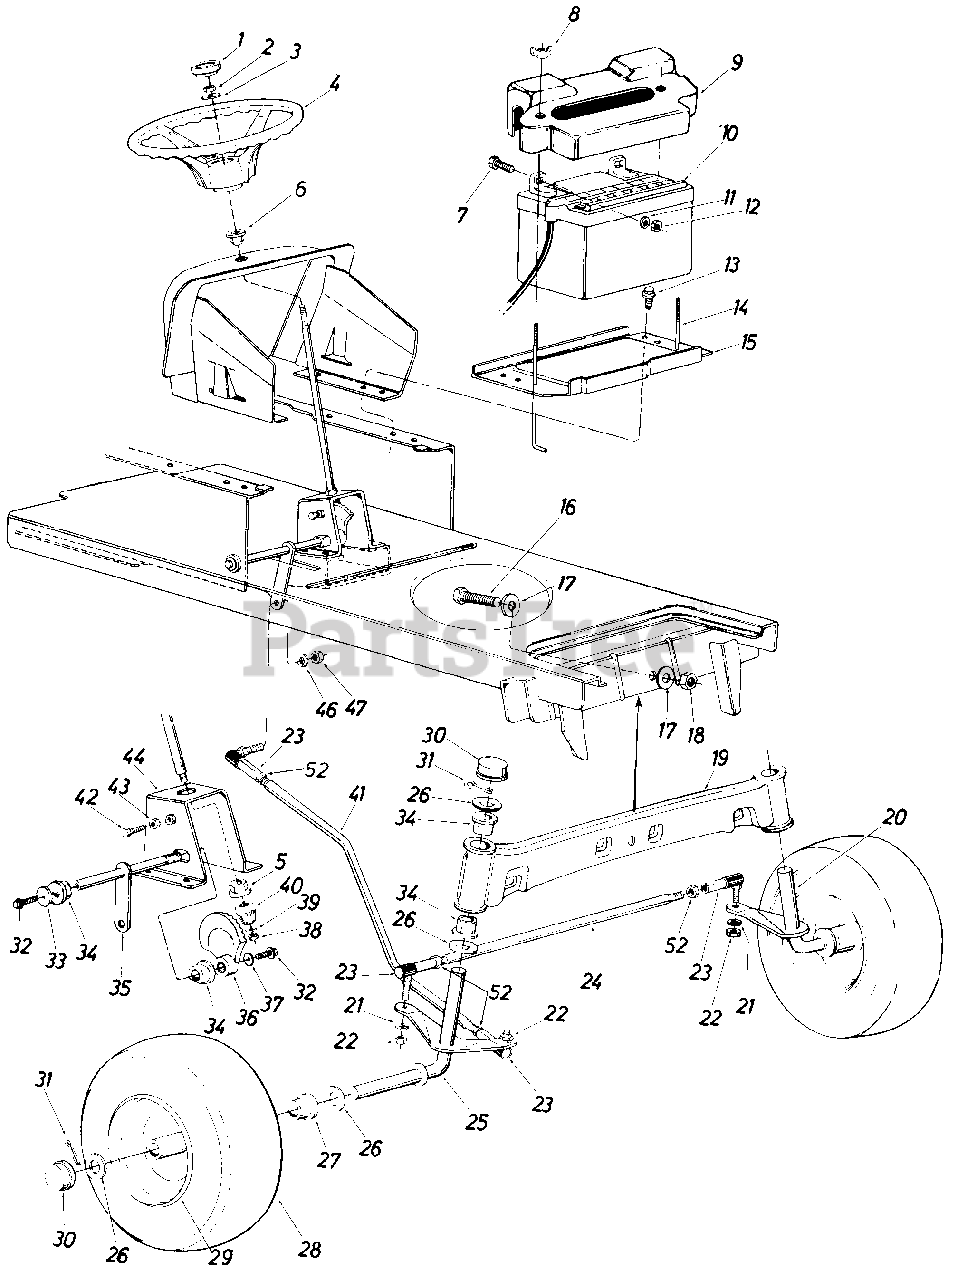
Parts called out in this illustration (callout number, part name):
1	Steering Wheel Cap
2	Hex L-Nut 5/16-24 Thd.
3	Bell-Wash. 5/16" I.D. x .87" O.D. x .060
4	Steering Wheel
5	Plastic Hex Bearing 518" I.D.
6	Steering Column Brg. .890" I.D.
7	Hex Scr. 1/4-20 x .62" Lg.
8	Wing Nut Plastic 1/4-20 Thd.
9	Battery Cover
10	12-V Battery
11	L-Wash. 1/4" Scr.
12	Hex Nut 1/4-20 Thd.
13	Hex Thd. Rolling Scr. 1/4-20 x.50" Lg.
14	Battery Hold Down Rod
15	Battery Plate
16	Hex Scr. 5/8-18 x 2.50" Lg.
17	Flat Wash. .66" I.D. x 2.25" O.D. x .17
18	Hex Cent. L-Nut 5/8-18 Thd.
19	Front Pivot Bar Ass'y.
20	Front Axle Ass'y. L.H.
21	L-Wash. 3/8" Scr.
22	Hex Nut 3/8-24 Thd.
23	Ball Joint Ass'y.
24	Tie Rod
25	Front Axle Ass'y. R.H.
26	Fl-Wash. .780 I.D. x 1.59 O.D.
27	Flange Bearing
28	Front Wheel Ass'y. Comp.
29	Front Wheel Rim Only
30	Dust Cover
31	Cotter Pin 5/32" Dia. x 1.00" Lg.
32	Hex Scr. 3/8-24 x .75" Lg. Grade 5
33	Fl-Wash. 3/8 I.D. x 1.25 O.D. x .090
34	Flange Double "D" Brg. .753 I.D.
35	Steering Arm Shaft Ass'y.
36	Side Gear Steering
37	Bell-Wash. 3/8" I.D.
38	Hex Cent. L-Nut 5/16-24 Thd.
39	Fl-Wash. 5/16" I.D. x .62 O.D. x .059
40	Pinion Gear Steering
41	Drag Link
42	Hex Nylon Scr. 3/8-16 x 1.25" Lg.
43	Hex Nut 3/8-16 Thd.
44	Steering Gear Sup. Ass'y.
46	L-Wash. 3/8" I.D.
47	Hex Nut 3/8-24 Thd.
52	Hex Jam Nut 3/8-24 Thd.
